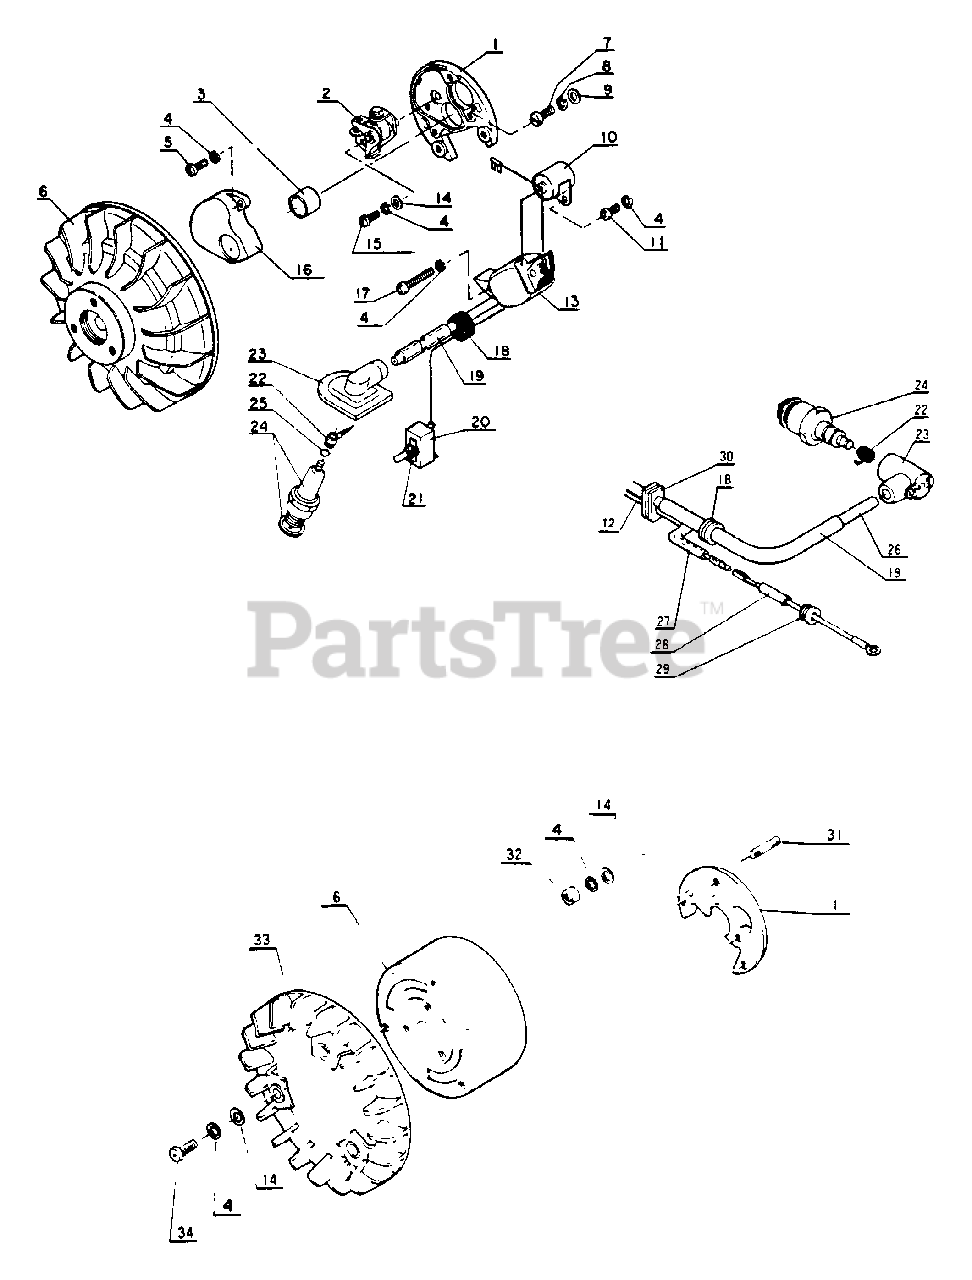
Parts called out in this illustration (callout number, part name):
1	PLATE, STATOR
2	CONTACT POINT SET
3	CAM
4	LOCKWASHER - 4
5	SCREW
6	FAN
7	SCREW
8	WASHER - SPRING
9	WASHER
10	CONDENSER
11	SCREW - 4X8
12	Stop lead cord
13	COIL, IGNITION
14	SCREW - 4X8
15	SCREW - 4X8
16	Brecher cover
17	SCREW - 4X20
19	TUBE
20	SWITCH, IGNITION
21	CAP
22	TERMINAL, SPARK PLUG CAP
23	CAP, SPARK PLUG
24	SPARK PLUG -- BM-6A
25	Spark plug clip
26	LEAD, SPARK PLUG
27	TUBE
28	Stop lead cord
29	BUSHING
30	BUSHING
31	STUD
32	NUT
33	FAN
34	SCREW - 4X12
